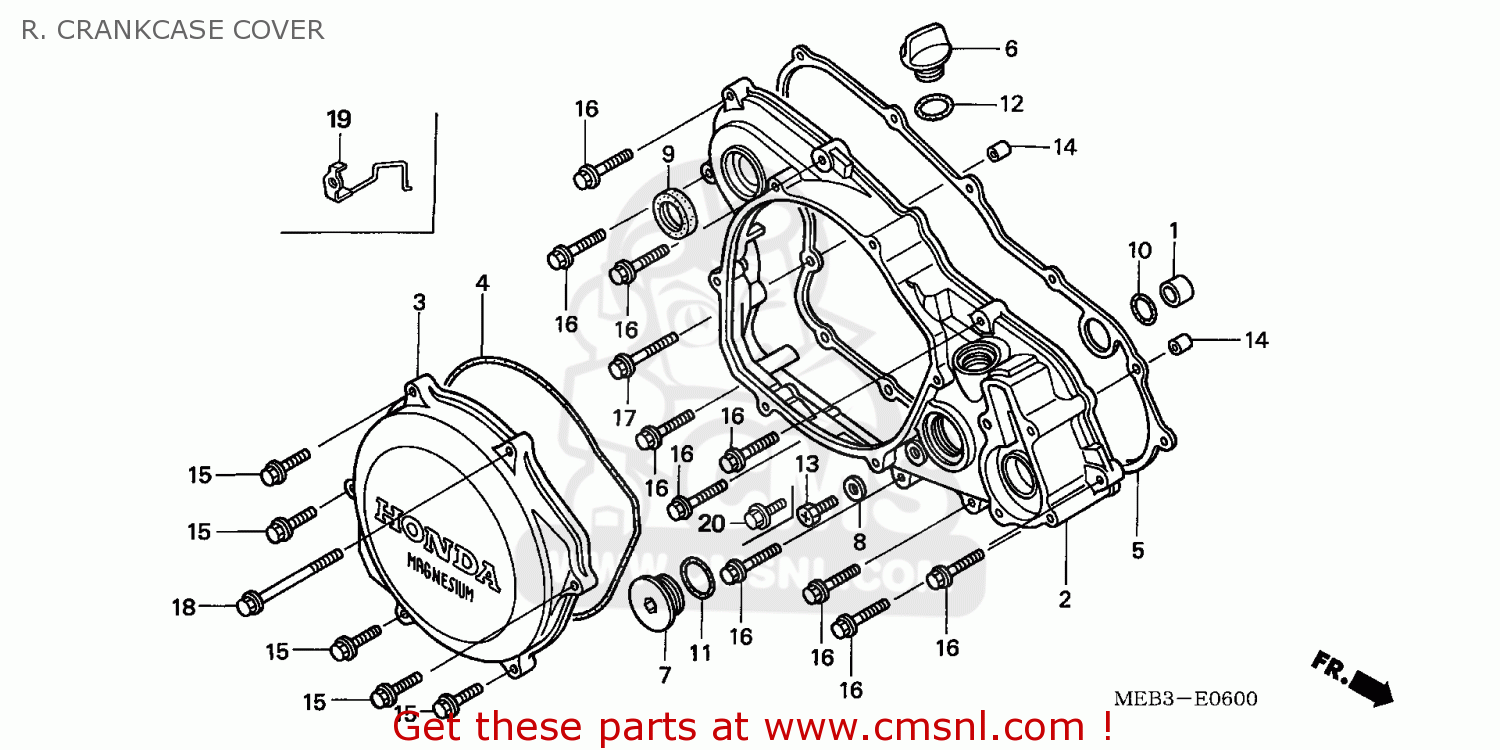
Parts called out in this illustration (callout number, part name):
1	COLLAR,WATER PASS
2	COVER,R CRANKCASE
3	COVER,CLUTCH
4	GASKET,CLCH COVER (NAS)
5	GASKET,R COVER (NAS)
6	CAP,OIL FILLER
7	CAP,30MM
8	WASHER,SEALING,6.
9	OIL SEAL,20X28X5
10	O-RING,178X24
11	O-RING,27X2
12	ORING 183
13	BOLT,RECESSED,6X1
15	BOLT,FLANGE,SH,6X25
16	BOLT,FLANGE,6X28
17	BOLT,FLANGE,6X35
18	BOLT,FLANGE SH 6X65
